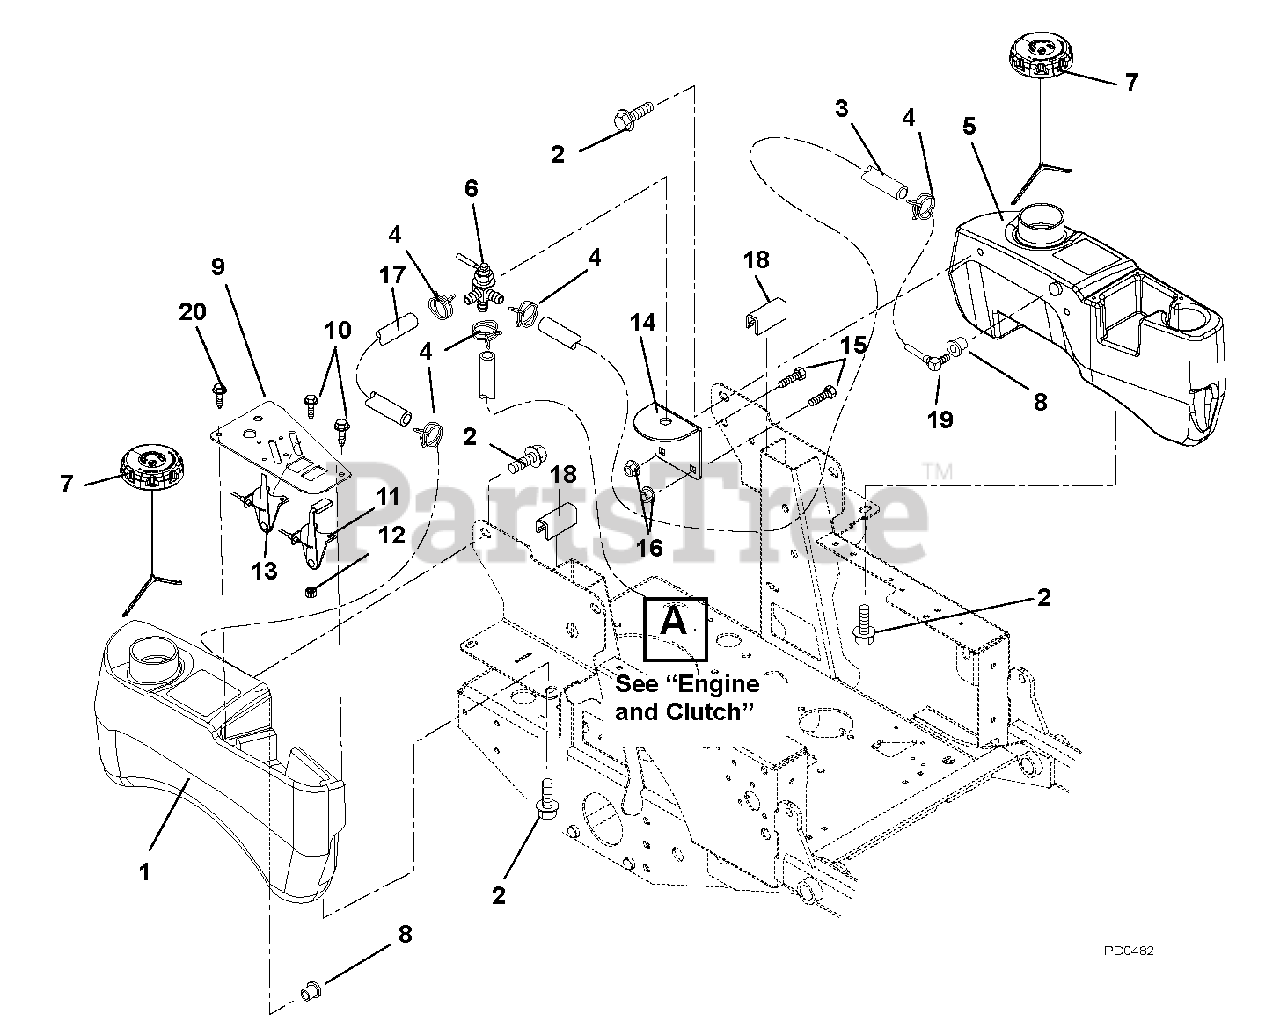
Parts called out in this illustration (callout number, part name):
1	Tank, Fuel Right Hand
2	Bolt, SEMS .31-18 x .62
3	Hose, Gas Line .25" I.D.
4	Hose, Clamp
5	Tank, Fuel Left Hand
6	Valve, Fuel
7	Cap, Fuel
8	Grommet (Orange color will not replace black color)
9	Panel, Control
10	Screw, Machine 10-24 x .50 Hex Washer Head
11	Cable, Throttle
12	Nut, Locking Nylon 10-24 with Insert
13	Cable, Choke
14	Bracket, Fuel Valve Mounting
15	Bolt, Round Head Square Neck .31-18 x .75
16	Nut, Nyloc Flange 5/16-18
17	Hose, Gas Line .25" I.D.
18	Cowl Strip 1.75" Long
19	Assembly, Small Tank Fuel Pick-up
20	Screw, Machine 10-24 x .38
